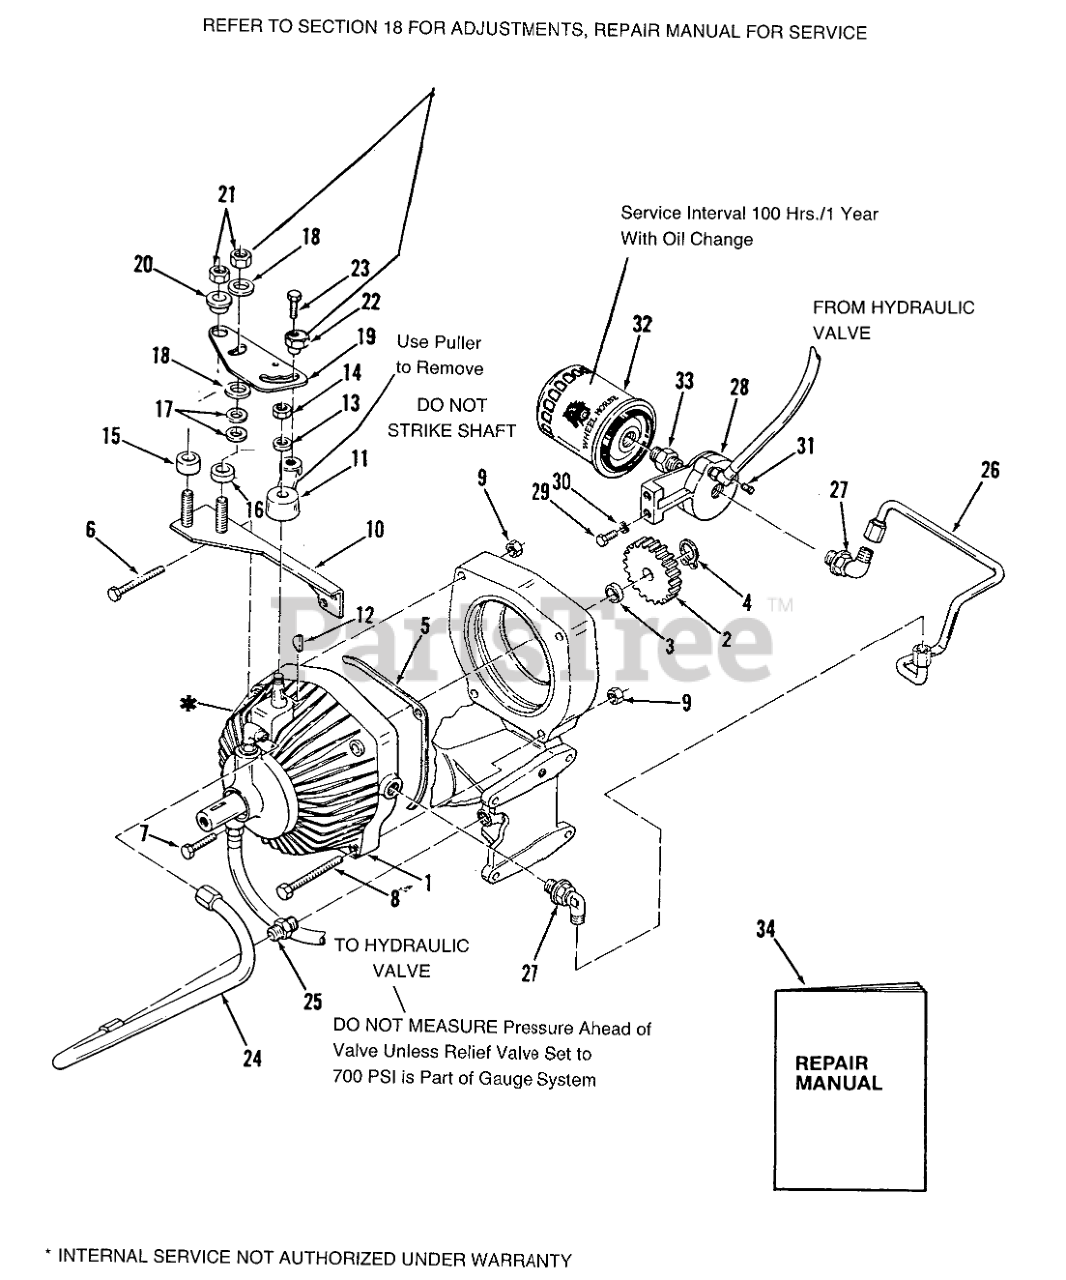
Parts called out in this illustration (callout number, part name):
1	Pump & Motor
2	GEAR 20 TEETH DRIVE
3	SPACER GEAR
4	SNAP RING- 5/8 EXT
5	GASKET
6	H H C S
7	Bolt
8	Bolt 3/8-16 x 6 1/2
9	Nut
10	ASSY-PLATE B
11	ARM-SPEED CONTROLB
12	Key #5 Woodruff
13	Washer
14	Eslok Nut
15	SPACER-PIVOT
16	SPACER-FRICTION
17	WASHER-SPRING DISC
18	FRICTION WASHER
19	CAM-SPEED CONTROL (NS)
20	CAM-SPACER
23	Bolt
24	ASSY-TUBE SUCTION
25	FITTING-TUBE
26	ASM-TUBE FILTER OUTL
27	ELBOW
28	BASE-FILTER
29	Bolt
30	Lockwasher
31	PLUG 1/4 PIPE ALLEN
32	Filter-Oil
33	FITTING
34	Repair Manual
